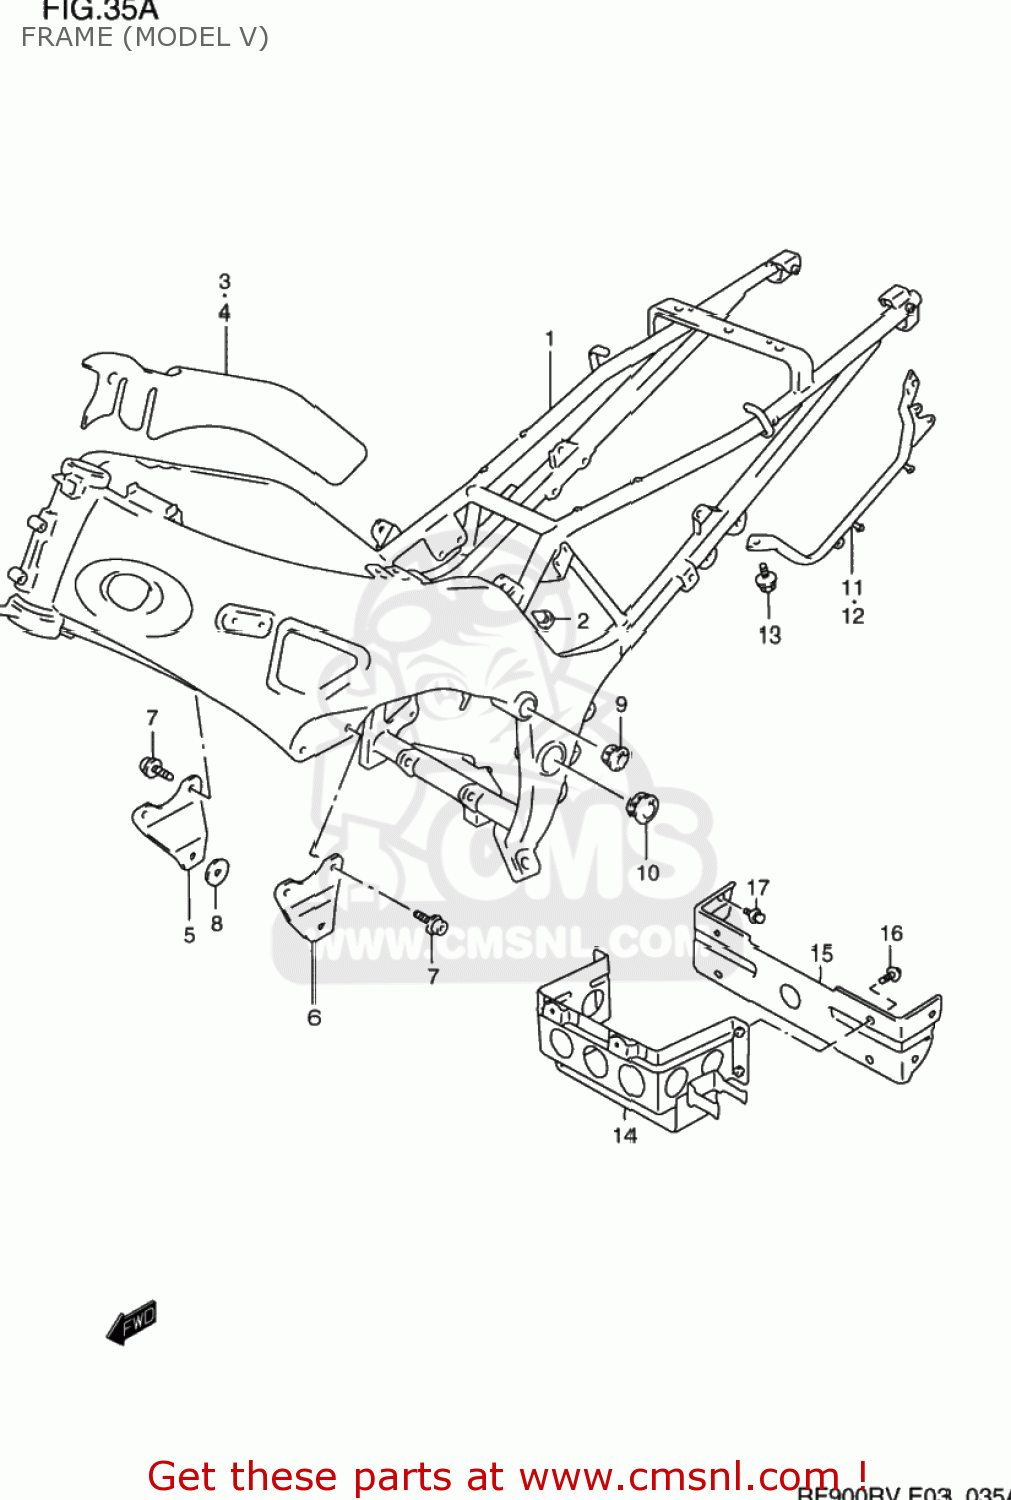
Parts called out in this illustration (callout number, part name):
1	FRAME COMP
2	PLUG(OD:10)
3	SHIELD,FRAME HEAT,RIGHT
4	SHIELD,FRAME HEAT,L
5	PLATE,ENG MTG,R
6	PLATE,ENG MTG,L
7	BOLT
8	WASHER (10.5X38X1.6)
9	CAP,FRAME BOSS,L
10	CAP,FRAME PIVOT
11	GRIP COMP,REAR,RIGHT
12	GRIP,RR,L
13	BOLT
14	HOLDER,BATTERY
15	BRACKET,BATTERY HOLDER
16	BOLT
17	BOLT
